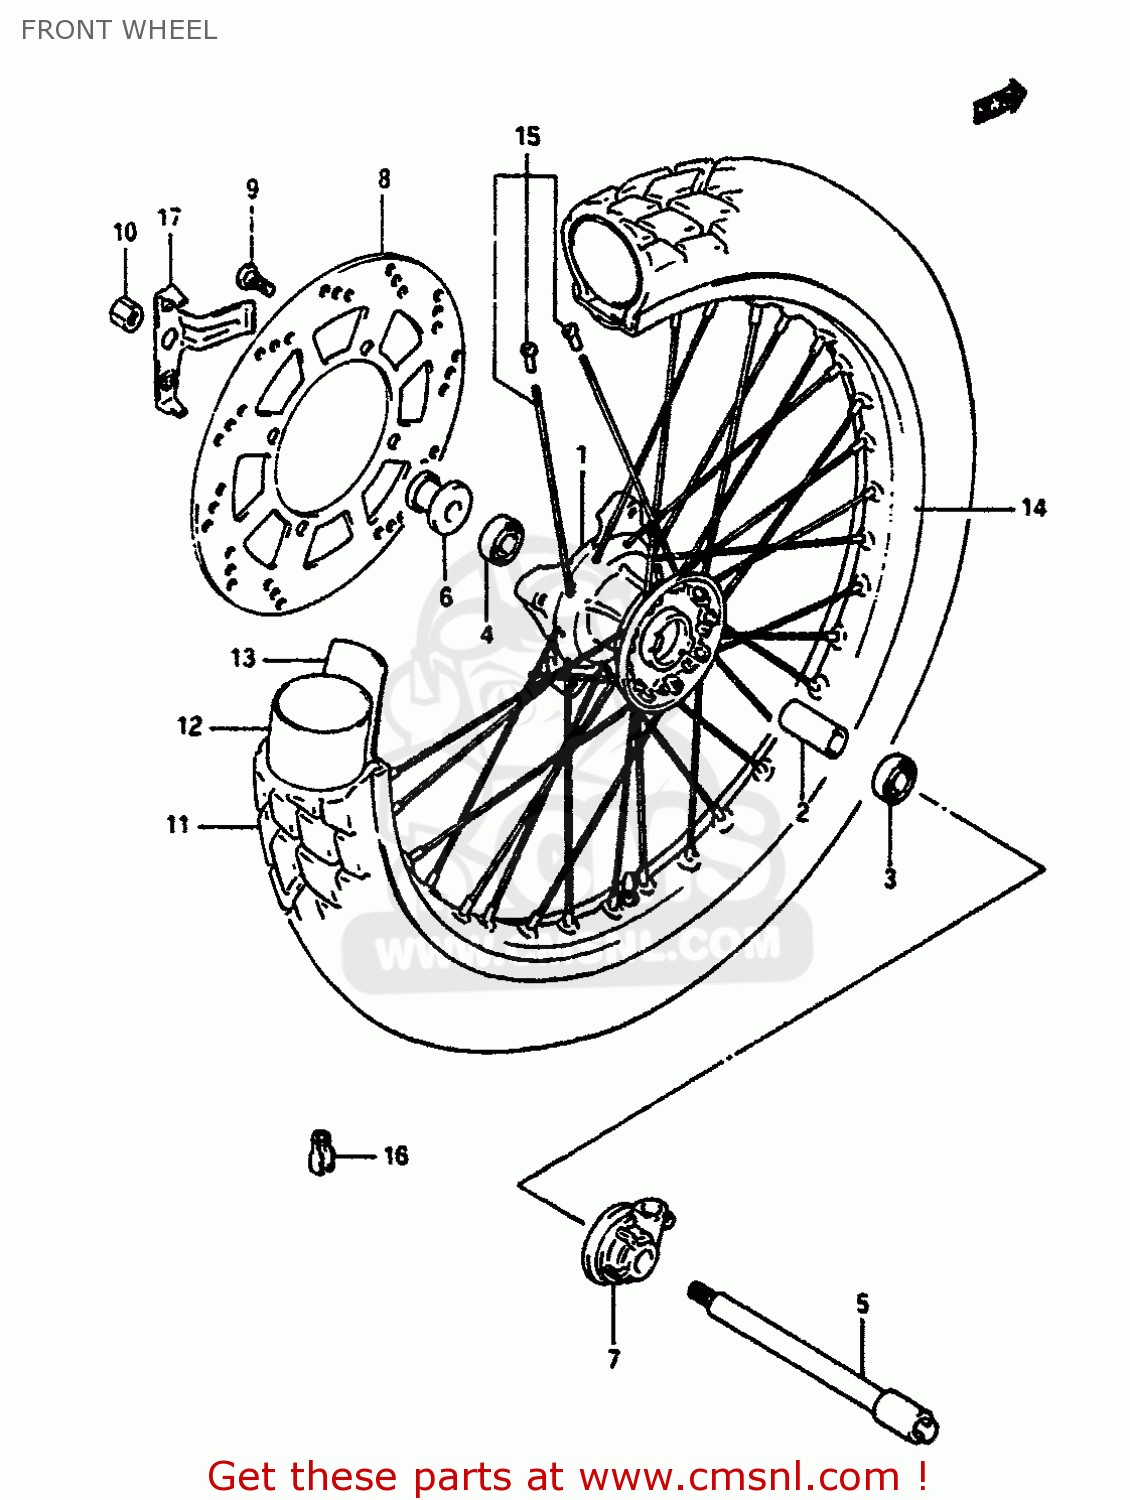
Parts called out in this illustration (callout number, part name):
1	HUB,FRONT WHEEL
2	SPACER,FR HUB BEARING
3	BEARING(15X32X15.9)
4	BEARING
5	AXLE,FR
6	SPACER,FRONT AXLE,LEFT
7	BOX ASSY,SPEEDOMETER GEAR
8	DISC,FR BRAKE
9	BOLT,BRAKE DISC
10	NUT
11	TIRE,FRONT (90/90-21 54S)
12	TUBE ASSY
13	PROTECTOR
14	RIM,FR WHEEL(21X1.85)
15	SPOKE SET,FR WHEEL
16	BALANCER,WHEEL
17	PLATE,PROTECTOR SET
